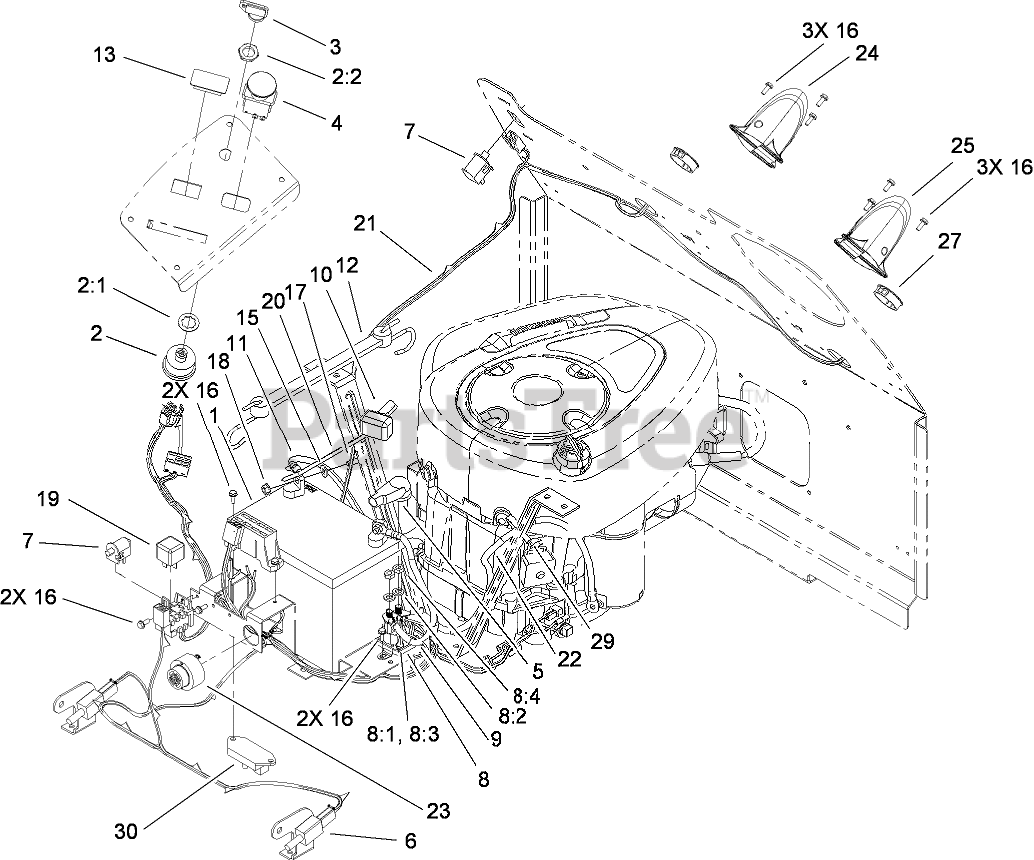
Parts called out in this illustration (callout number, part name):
1	BATTERY
2	Key Switch ASM
2:1	WASHER-TOOTH, INTERNAL
2:2	NUT-HH
3	KEY-IGNITION
4	SWITCH-PTO
5	BOOT-TERMINAL
6	SWITCH
7	SWITCH-BAIL
8	SWITCH-SOLENOID
8:1	WASHER-LOCK
8:2	WASHER-LOCK
8:3	NUT-HEX
8:4	NUT-JAM
9	CABLE-BATTERY, POSITIVE
10	BOOT-INSULATOR, TERMINAL
11	CABLE-NEGATIVE, BLACK
12	HOLDDOWN-BATTERY
13	PLUG-HOLE
15	WASHER-FLAT
16	SCREW-TAPTITE
17	SCREW-HH
18	NUT-HF
19	RELAY
20	TIE-CABLE
21	HARNESS-WIRE
22	WIRE-21 INCH
23	ALARM-TONE, DUAL
24	BAG SENSOR ASM
25	BAG SENSOR ASM
27	BUSHING-HARNESS, WIRE
29	CLAMP-HOSE
30	MODULE-DELAY
